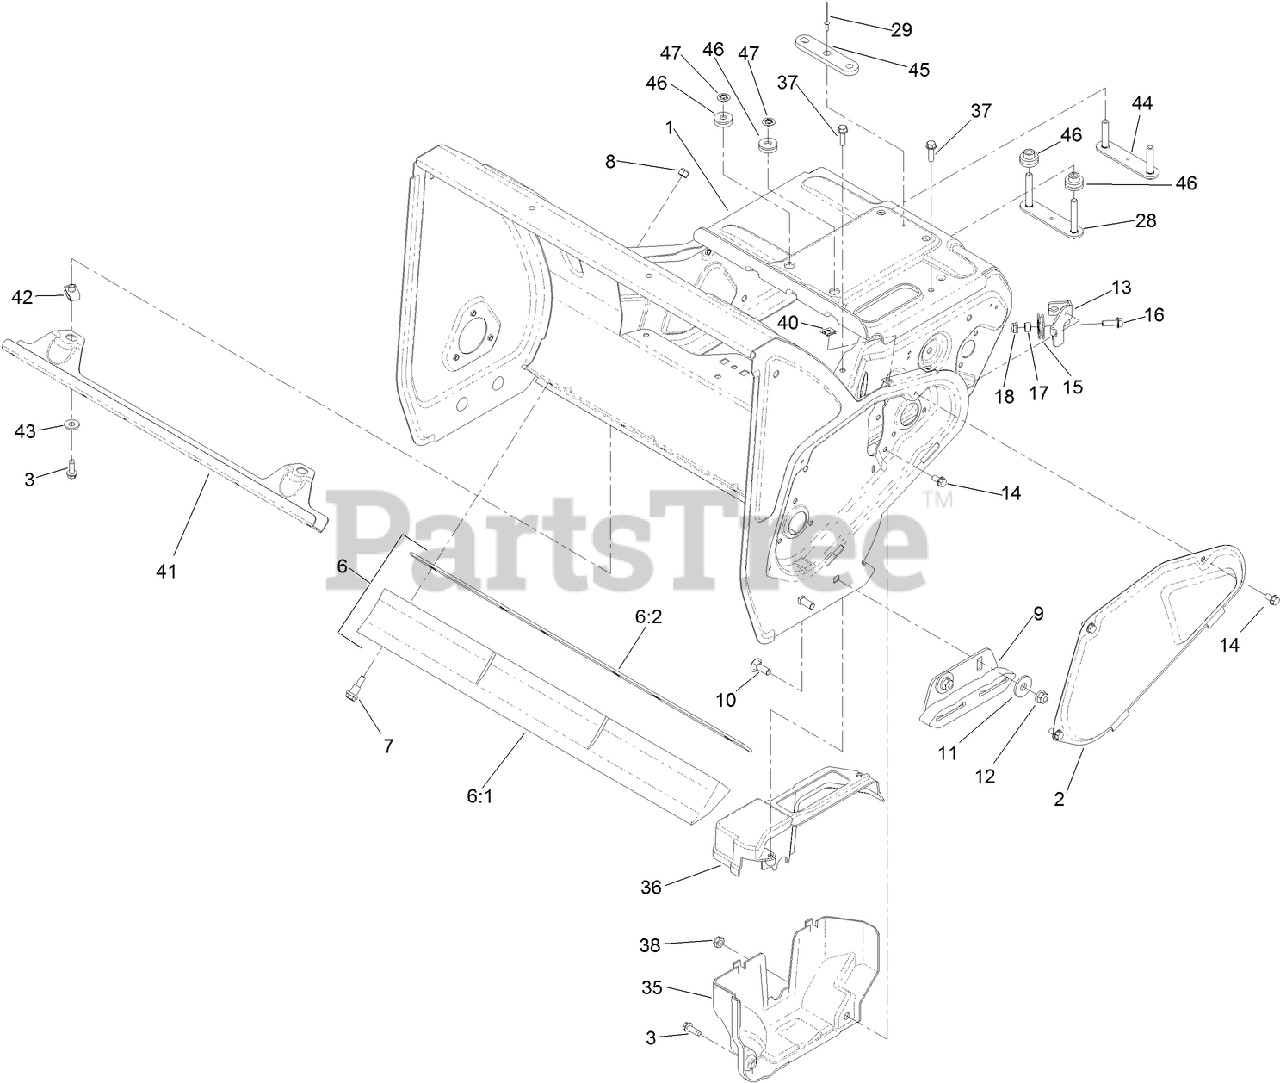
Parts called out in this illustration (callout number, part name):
2	COVER-BELT
3	SCREW-HWHTF
6	SCRAPER ASM
6:1	BLADE-SCRAPER
6:2	FOAM-SCRAPER
7	BOLT-SHOULDER
8	NUT-LOCK, NI
9	SKID ASM
10	SCREW-CARR
11	WASHER
12	NUT-HF, NI
13	BRACKET-CABLE
14	SCREW-HWH
15	CABLE-PULLEY
16	SCREW-HHF
17	SPACER-BLADE, ROTOR
18	NUT-HF
28	PLATE-STUD, FRONT
29	RIVET
35	COVER-BELT, LOWER
36	COVER-BELT, UPPER
37	SCREW-HWH
38	NUT-LOCK, NI
40	NUT-SPEED
41	SUPPORT-FRAME, LOWER
43	WASHER-FLAT
44	PLATE-STUD, REAR
45	PLATE-SPACER
46	ISOLATOR-ENGINE
47	RING-RETAINING, BOLT
